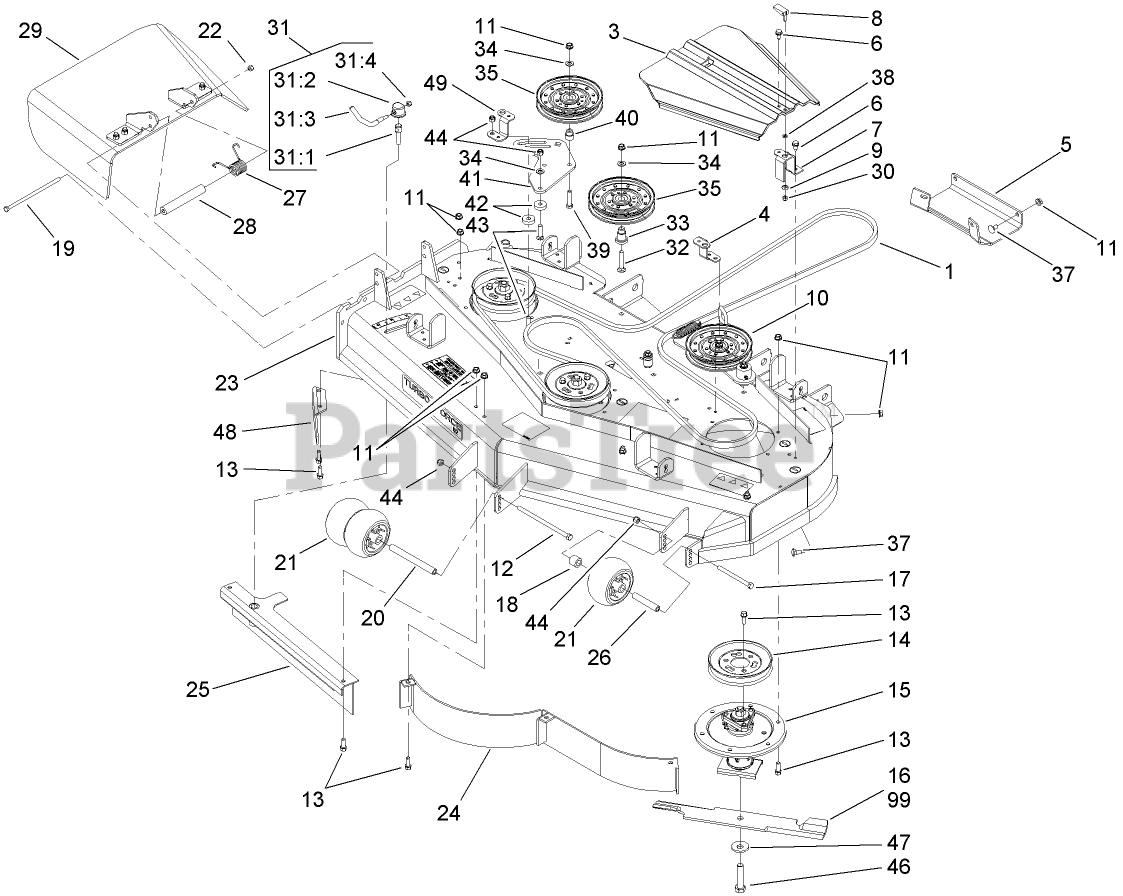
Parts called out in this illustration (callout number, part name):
1	BELT-V
3	COVER-BELT
4	BRACKET-COVER, TALL
5	Plate-Skid
6	SCREW-HWHTF
7	BRACKET-COVER
8	HANDLE-LATCH, SWELL
9	BUSHING-LATCH, SWELL
10	SPRING IDLER ASM
11	NUT-HHF, WHIZ
12	SCREW-HH
13	SCREW-HWH
14	PULLEY
15	SPINDLE ASM
16	BLADE-18IN, HI FLOW
17	SCREW-HH
18	TUBE-SPACER
19	SCREW-HH
20	SPACER-WHEEL
21	ROLLER-SCALP, ANTI
22	NUT-LOCK, NI
23	DECK DECAL ASM
26	TUBE-SPANNER
27	SPRING-TORSION
28	SPACER
29	RUBBER DEFLECTOR ASM
30	NUT-LOCK, HH
31	LEVER ASM
31:1	Screw-Lock
31:2	CAP-LOCK
31:3	Lever-Lock
31:4	NUT-LOCK, NI
32	SCREW-CARR
33	MOUNT-PULLEY
34	WASHER-FLAT
35	Idler-Flat
37	SCREW-CARR
38	WASHER
39	SCREW-HH
40	BUSHING-IDLER
41	PLATE-IDLER
42	Spacer
43	SCREW-CARR
44	NUT-LOCK, NI
46	Screw-Cap
47	Washer-Blade Bolt, Heavy
48	BAFFLE-DISCHARGE
49	BRACKET-COVER, SHORT
